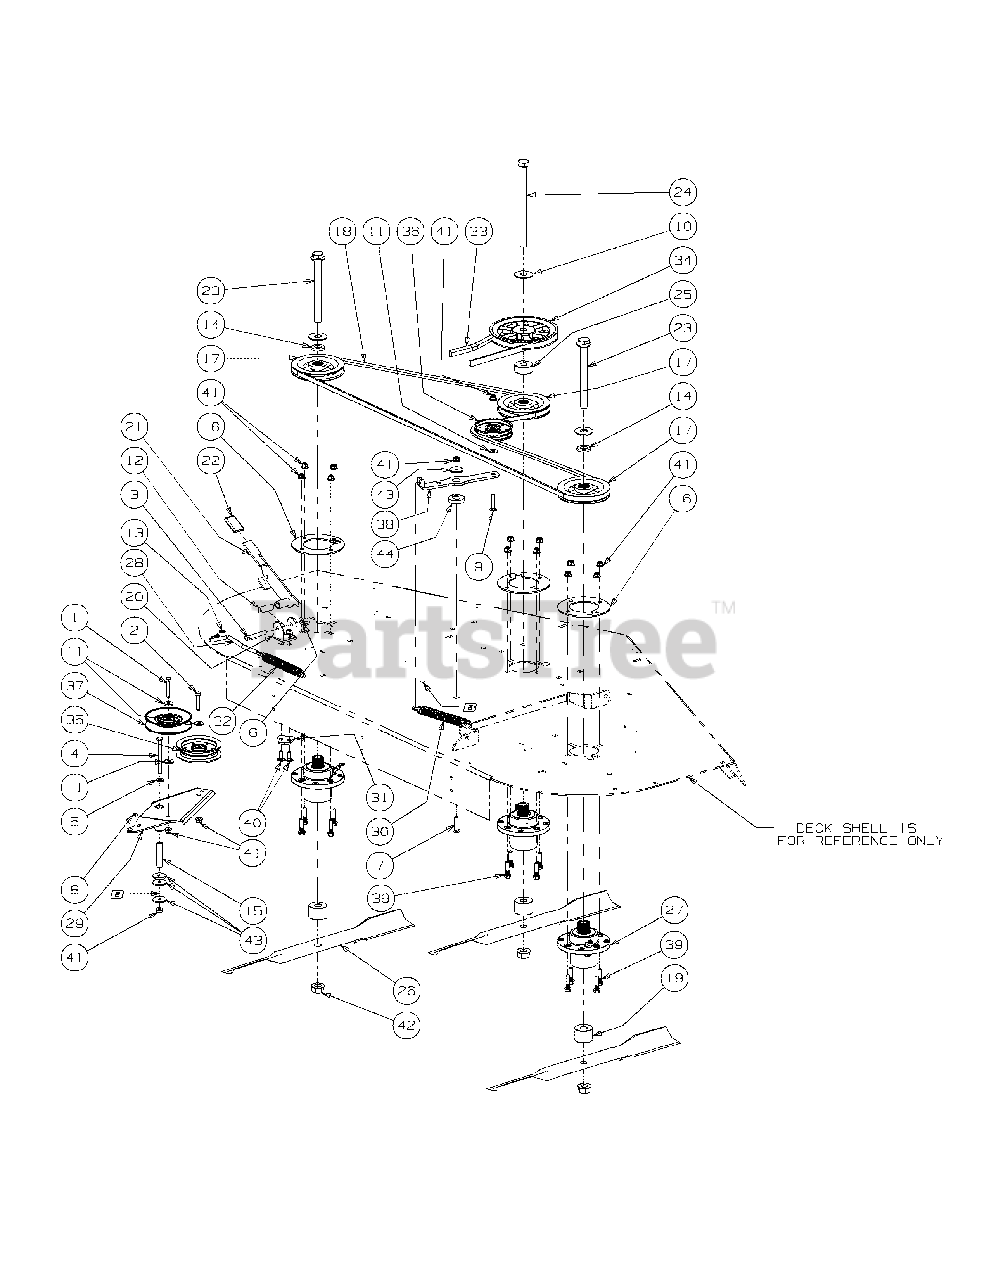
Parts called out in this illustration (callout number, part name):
1	Hex Cap Screw, 3/8-16 x 2.00
2	Hex Cap Screw, 3/8-16 x 1-3/4
3	Hex Cap Screw, #/8-16 x 2-1/2
4	Hex Cap Screw, 3/8-16 x 4.00
5	Washer, 3/8
6	Flange Lock Hex Nut, 3/8-16
7	Carriage Bolt, 3/81-6 x 1-1/2
8	Grease Fitting, 1/4-28 x 3/16
9	Hex Carriage Screw, 3/8-16, 1.75
10	Flat Washer, .781 ID 2.00 OD, .105
11	Flat Washer, .406 ID, 1.0 OD, .105
12	Spacer, .39 ID x .63 OD x 1.75
13	Cotter Pin, .072 x 1.12 Long
14	Spacer .812 ID x .268 LG
15	Spacer, .39 ID x .625 OD x 2.75
16	Aluminum Spindle Support Plate
17	V-Pulley, 5.75 OD
18	V-Belt, B Section x 124.0 Lg
19	Spacer, .760 ID x 2.00 OD x 1.28
20	Tension Idler U-Bracket
21	Handle Tension Weldment
22	Tension Idler Handle Grip
23	Hex Cap Screw, 3/4-16, 7.50
24	Hex Cap Screw, 3/4-16, 9.50
25	Spacer, .76 ID x 2.0 OD x .790
26	Bahia Blade, 25.0, .756 ID
27	Aluminum Spindle Assembly
28	Spring Tension Rod
29	Idler Arm Assembly includes:
30	Extension Spring, .94 x OD x 7.57
31	Adaptor Plate
32	Extension Spring, .94 OD x 7.72 Lg
33	V-Belt, B Section x 107.0
34	V-Pulley, 7.450 OD x .750 Bore, Cast
35	Idler Pulley, 4.06 OD
36	Idler Pulley, 4.06 Dia.
37	Idler Pulley, 5.06 Dia.
39	Bolt, 3/8-16 x 1.5
40	Carriage Bolt, 3/8-16 x 1
41	Nut, 3/8-16, Nylon Flange Lock
42	Flange Hex Nut, 3/4-16
43	Washer, .390 x 1.500 x .134
